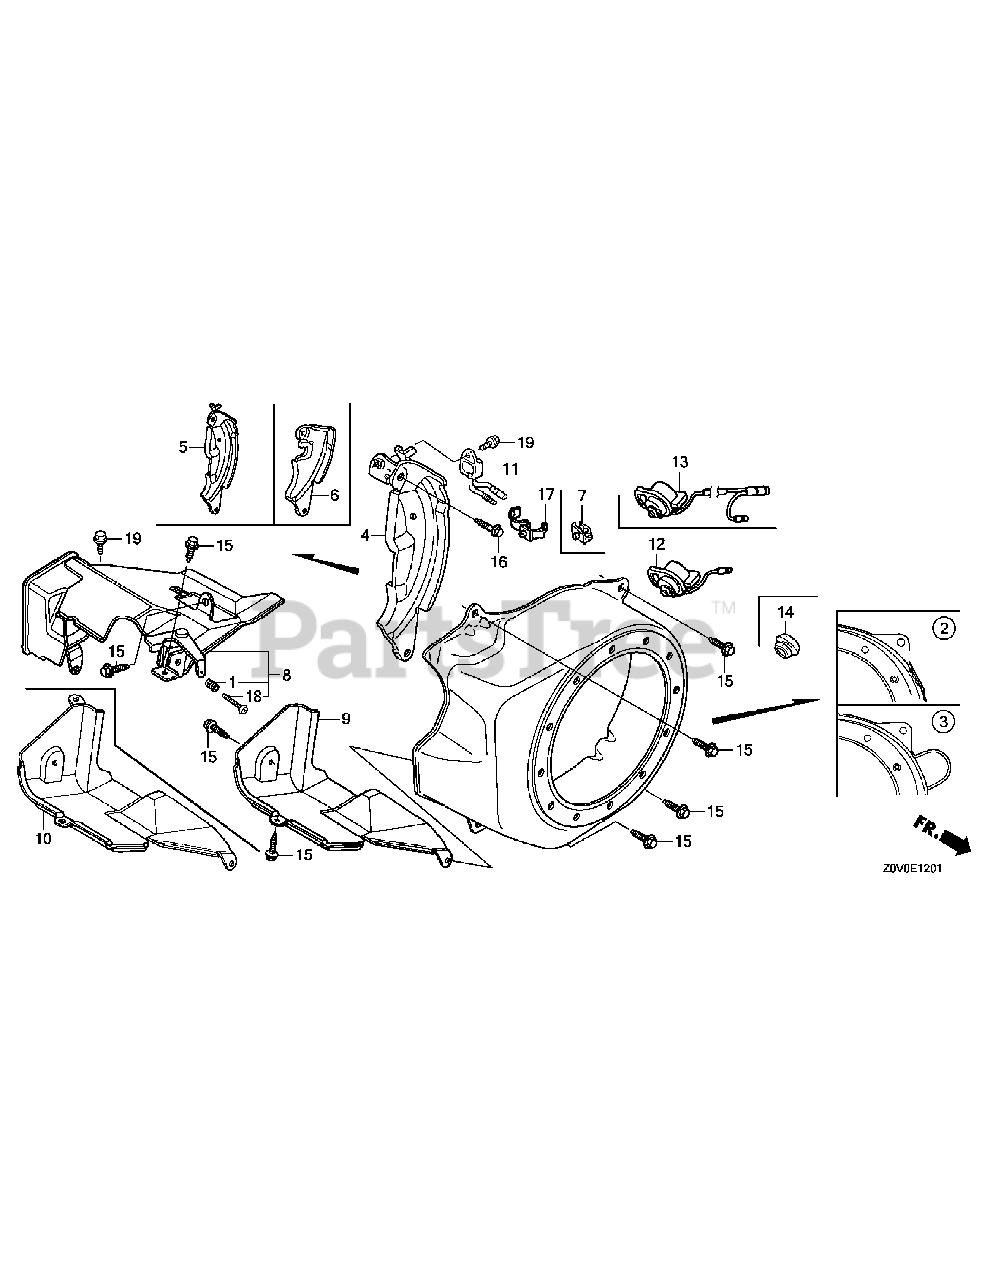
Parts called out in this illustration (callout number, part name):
1	Spring, Control Adjusting
2	Cover Comp., Fan
3	Cover Comp., Fan
4	Plate Comp., Side(Oil Alert)
5	Plate, Side(Std.)
6	Plate, Side(Starter Motor)
7	Clamp, Cord
8	Shroud Assy., Upper
9	Shroud Comp.
10	Shroud Comp., Lower
11	Alert Unit, Oil
12	Switch Assy., Engine Stop
13	Switch Assy., Engine Stop
14	Grommet, Drain Hole
15	Bolt, Flange, 6X12(Ct200)
16	Bolt, Flange, 6X20(Ct200)
17	Clip, Harness
18	Screw, Pan, 5X35
19	Bolt, Flange, 6X8
